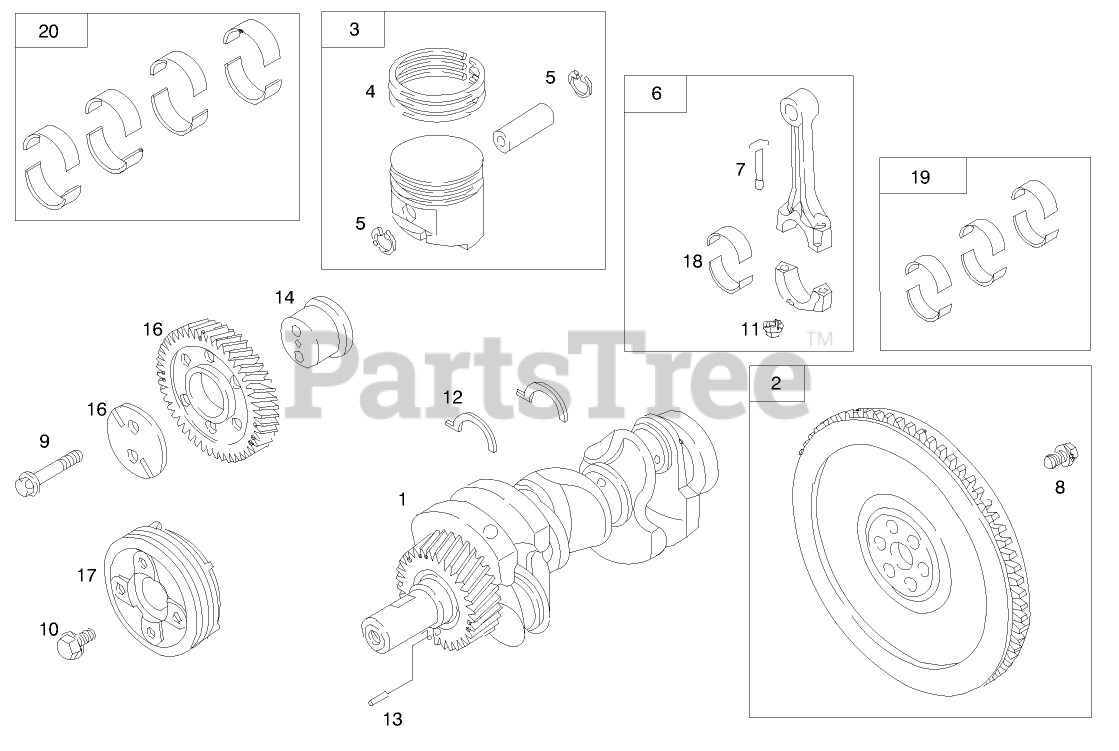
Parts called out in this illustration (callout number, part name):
1	CRANKSHAFT
2	FLYWHEEL, INSTEAD USE 99-9267
4	RING SET
5	LOCK-PIN, PISTON
6	SEE PARTS BULLETIN #949
7	SCREW
8	SCREW-HEX
9	SCREW-HEX
10	SCREW-HEX
11	NUT-HEX
12	SHIM-ENDPLAY
13	PIN-LOCATING
15	SHAFT-GEAR
16	PLATE-GEAR, IDLER
20	MAIN BEARING SET (SET OF 8)
